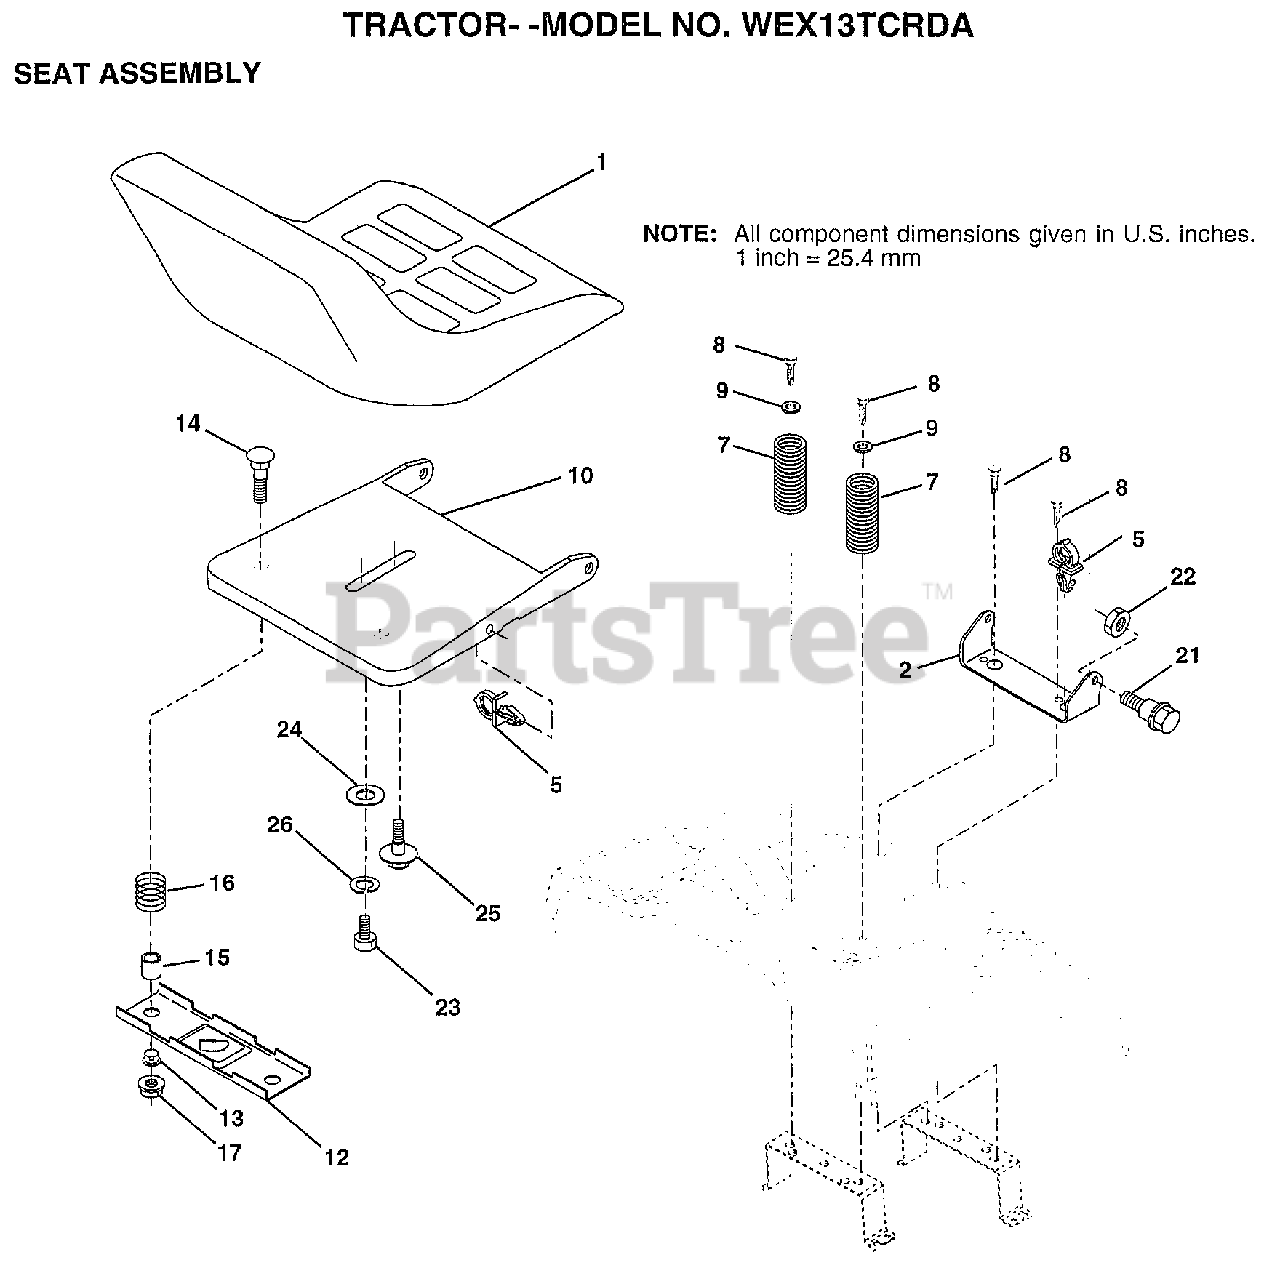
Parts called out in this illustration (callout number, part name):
2	BRACKET PVT SEAT
5	CLIP.PUSH-IN.HING
7	SPRING COMPRESSIO
8	SCREW GTV
9	WASHER
10	PAN-SEAT
12	BRKT SWITCH
13	BUSHING
14	BOLT-RD HD SQ NK
15	SPLIT SPACER
16	SPRING
21	"BOLT,SHOULDER"
22	NUT
23	BOLT
24	WASHER
25	"BOLT,SHOULDER"
26	LOCKWASHER
